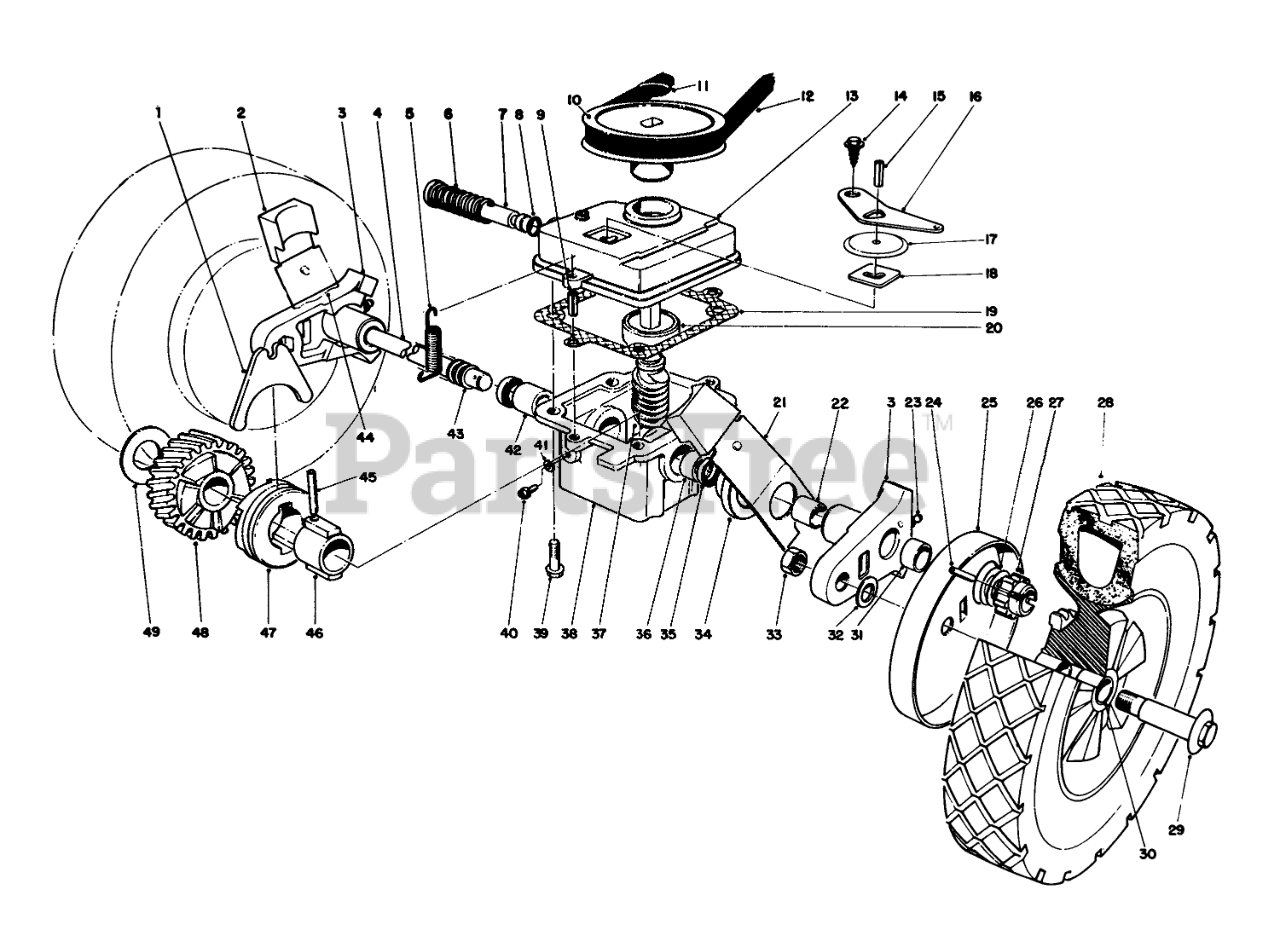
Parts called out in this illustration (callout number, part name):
1	SHIFTER FORK
2	KNOB-ARM
3	Pivot Arm (Incl. Ref. #22, 23 & 31)
4	DRIVE SHAFT (SERVCE)
5	TENSION SPRING
6	SPRING
7	SHIFTER ROD
8	O-RING
9	3/16 X 1/2 ROLL PIN
10	PULLEY
11	PUSH-ON 93-3236
12	V BELT
13	Gear Case Cover (Incl. Ref. #20)
14	Screw
15	PIN-ROLL
16	SHIFTER ARM
17	TRANS DUST COVER
18	LATCH PLATE
19	GASKET
20	BEARING
21	SPRING ARM ASM SP LH
22	BUSHING
23	FITTING-GREASE
24	Pin
25	WHEEL COVER
26	THRUST WASHER
27	PINION GEAR 14T
28	Wheel & Tire Assembly (Incl. Ref. #30)
29	WHEEL BOLT
30	BUSHING
31	BUSHING
32	WASHER
33	NUT-LOCK
34	CAP-END
35	SEAL-OIL
36	BUSHING
37	Worm Shaft 8 Gear (Incl. Ref. #48)
38	Gear Case (Incl. Ref. #35, 36 & 42)
39	Screw
40	NYLON SCREW
41	FILL PLUG GASKET
42	BUSHING
43	COVER-SHAFT, DRIVE
44	SPRING ARM ASM SP RH
45	COIL PIN
46	SLEEVE
47	CLUTCH JAW
48	Helical Gear
49	THRUST WASHER
